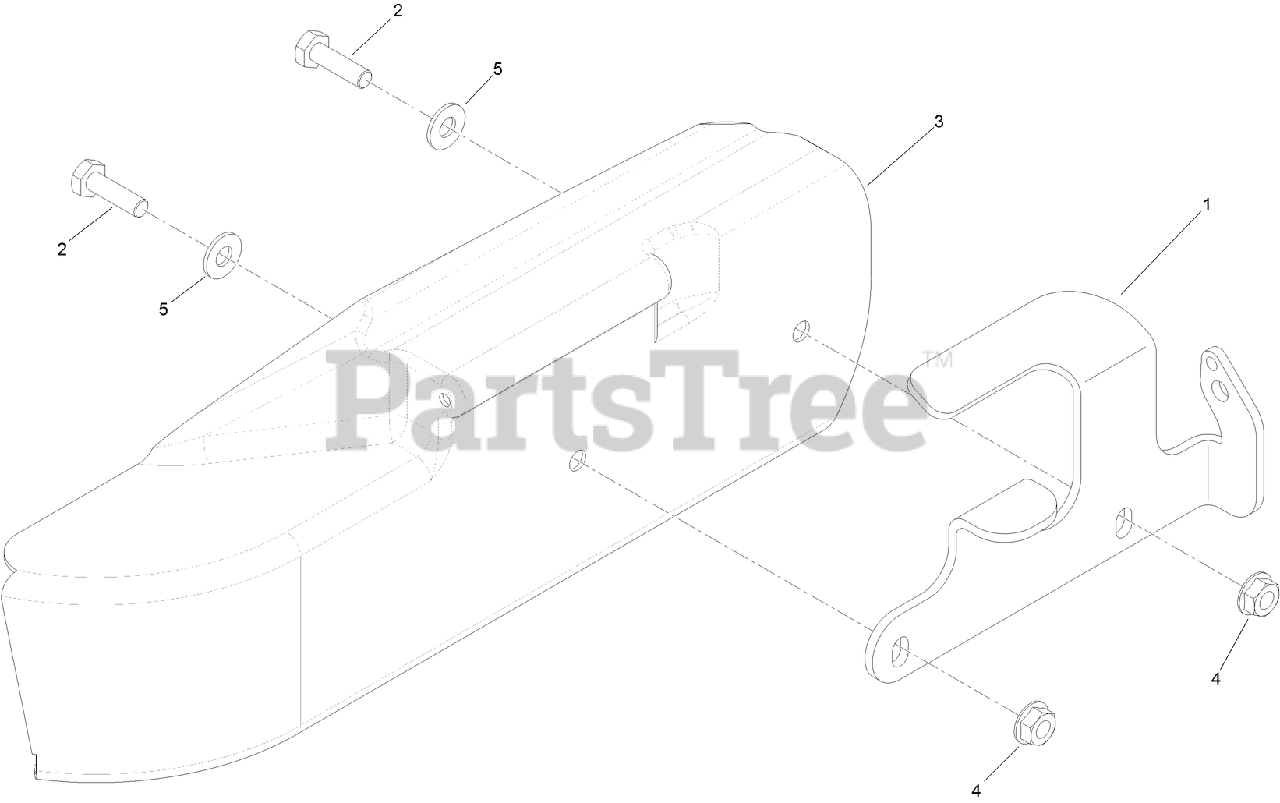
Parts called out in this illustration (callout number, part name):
1	BRACKET-DEFLECTOR, SIDE
2	SCREW-HH
3	DEFLECTOR-SIDE
4	NUT-HF
5	WASHER-FLAT
